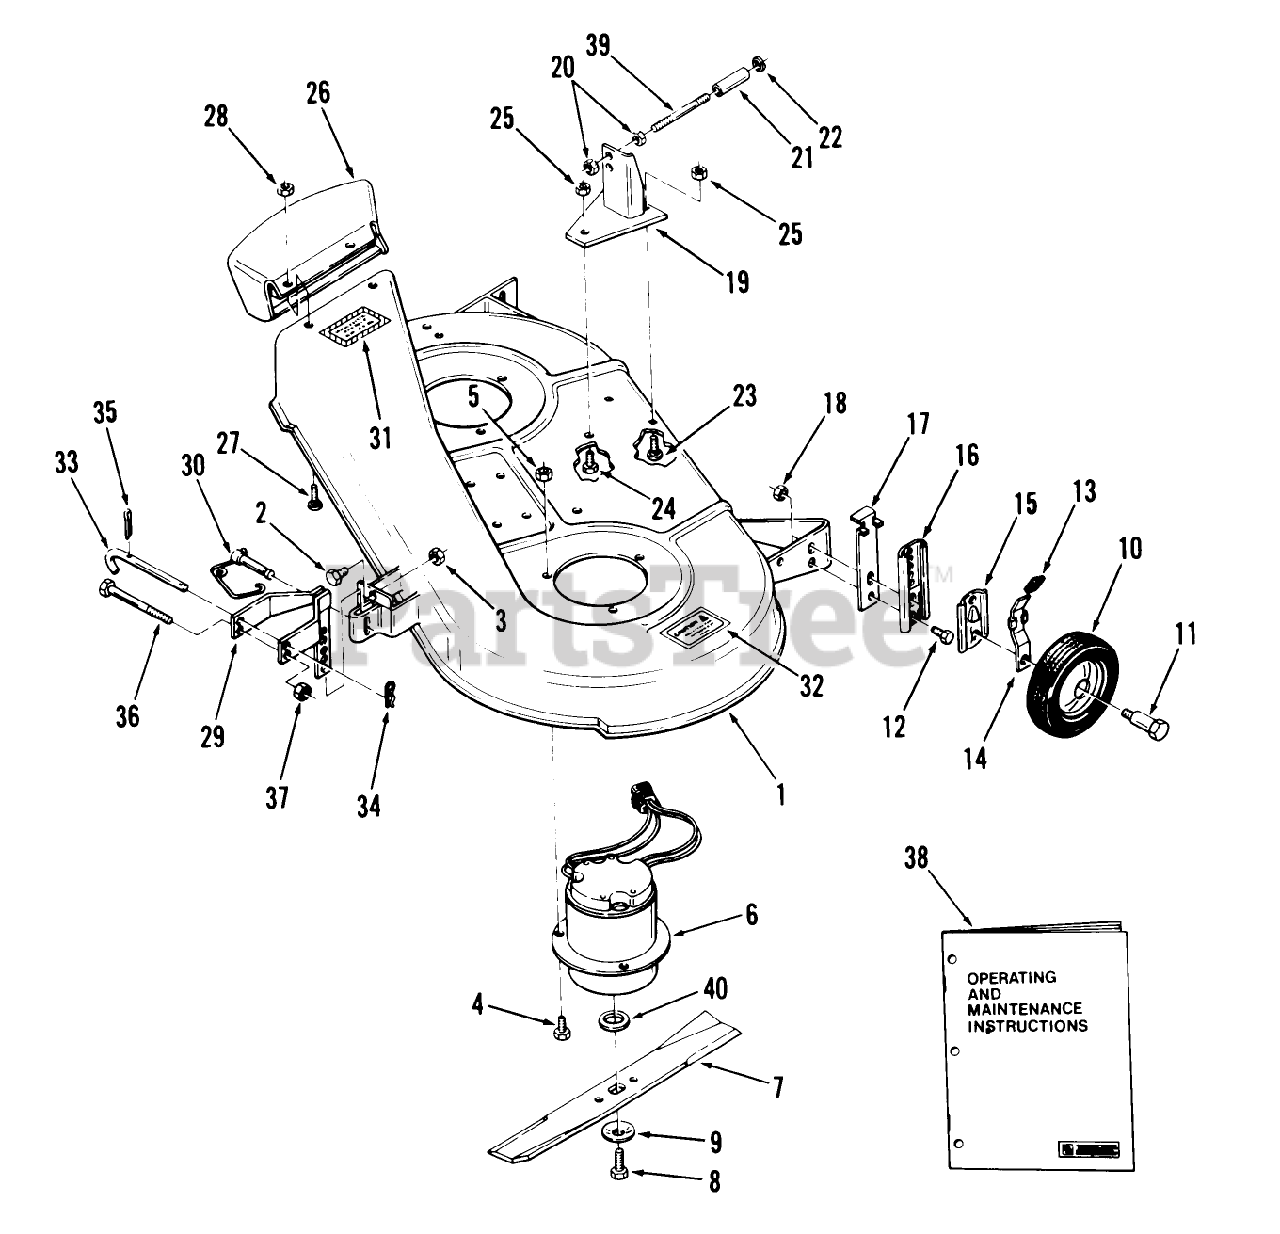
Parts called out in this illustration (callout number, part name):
14	HT ADJ SPRING LEVER
15	HT ADJ SLIDE
27	CARRIAGE BOLT -4
34	Hairpin
38	Owners Manual (Alternate 810108R1)
